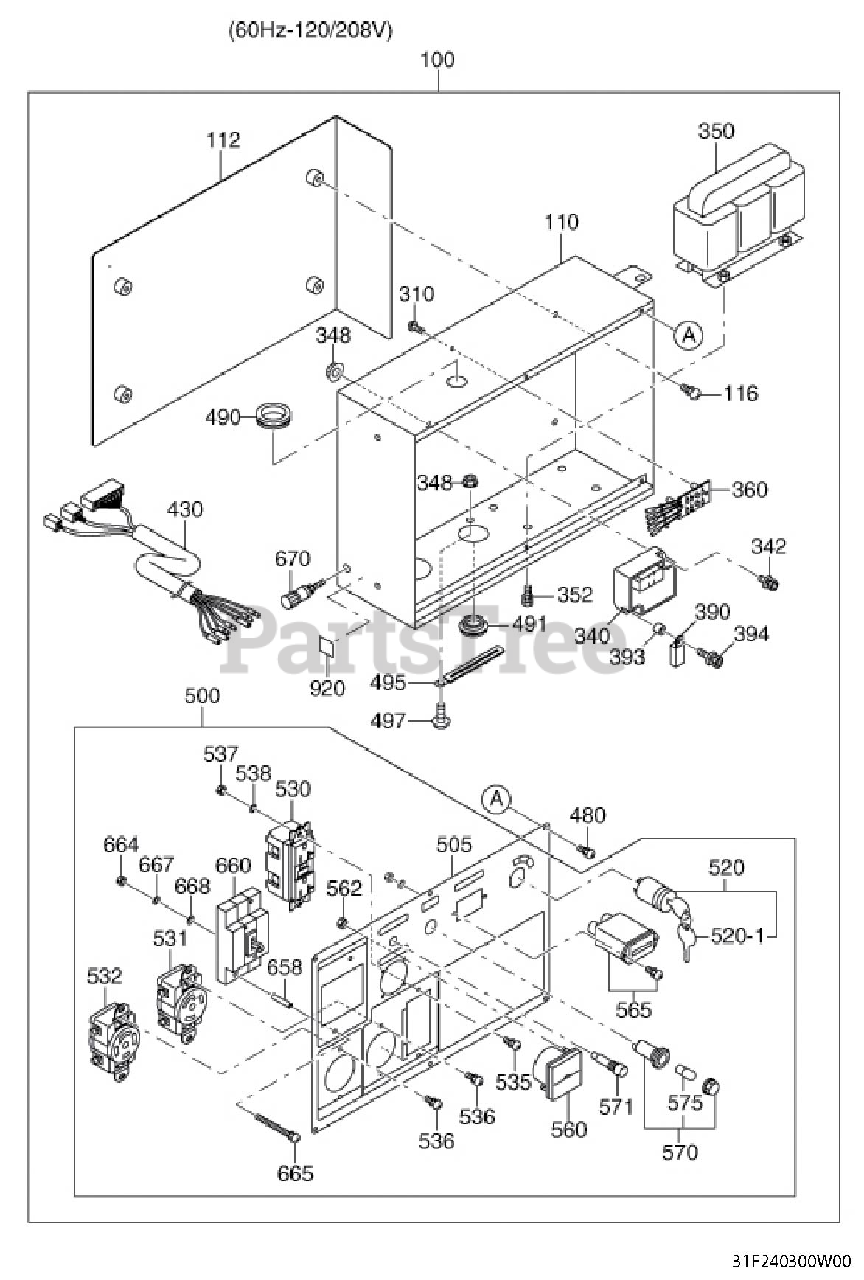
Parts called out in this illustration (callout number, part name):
100	CONTROL BOX AY
110	CONTROL BOX UN
112	PLATE
116	SCREW AND WASHER
310	SCREW
340	ECU(0/S & R/C) CP
342	SCREW AND WASHER AY
348	FLANGE NUT
350	CURRENT TRANS
352	BOLT AND WASHER
393	SPACER
394	SCREW
480	SCREW AND WASHER AY
490	GROMMET
495	CLAMP
497	FLANGE BOLT
500	CONTROL PANEL AY
505	CONTROL PANEL
520	SWITCH
530	AC CONCENT (GFCI)
531	AC RECEPTACLE
532	AC RECEPTACLE
535	SCREW and WASHER AY
536	SCREW and WASHER AY
560	VOLT METER
565	HOUR METER
570	PILOT LAMP CP
575	LAMP
658	SPACER
665	SCREW
670	TERMINAL BOLT
